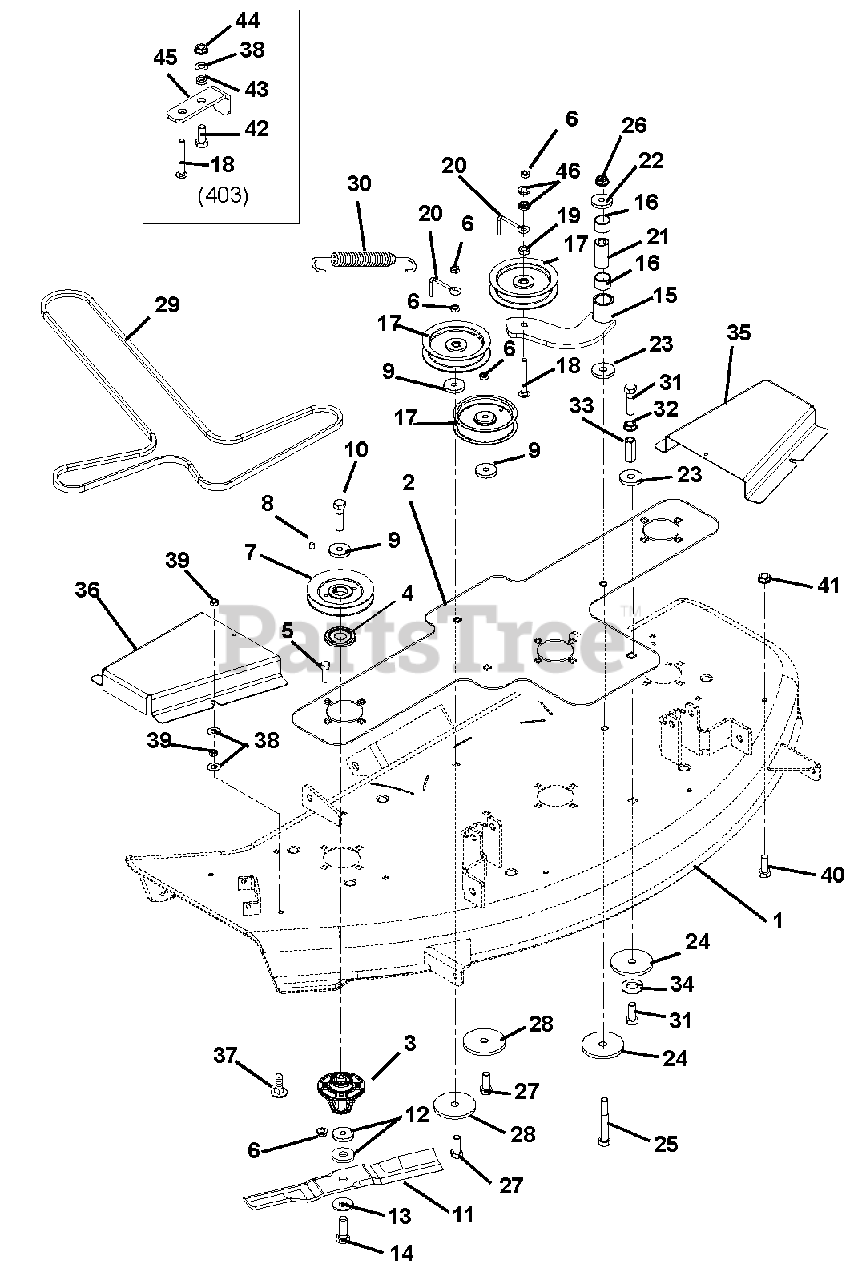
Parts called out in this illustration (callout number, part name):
1	Weldment 50" Deck (404)
2	Deck Doubler, (404)
3	Spindle Assembly
4	Dust Cap
5	Bolt, Round Head Square Neck .38-16 x 1.25
6	Nut .38-16 Flange Nyloc (404)
7	Sheave, Spindle 4.75 Dia. (404)
8	Key, Square .25 x .38 x .25
9	Washer, Flat Steel .406 x 1.50 x .245
10	Bolt, Hex .38-16 x 1.00 EP30 Grade 8
11	Blade, Mower (404)
12	Washer, Flat .640 x 1.81 x .250
13	Washer, Beveled .63 x 1.625 x .140
14	Bolt, Hex .62-18 x 1.75 Grade 8
15	Weldment, Idler Arm
16	Bearing, 1.00 x 1.12 x .75
17	Idler, Flat .38 x 4.00 x 1.06
18	Bolt, Round Head Square Neck .38-16 x 3.50 Grade 5 (404)
20	Finger, Belt (404)
21	Spacer, Powdered Metal
22	Washer, Flat Steel .511 x 1.44 x 125
23	Washer, Flat Steel .515 x 1.625 x .25
24	Washer, Flat Steel .531 x 3.00 x .25
25	Bolt, Hex .50-13 x 3.50 Grade 5
26	Nut, Locking-Top-Flange .50 - 13
27	Bolt, Hex .38-16 x 2.75 Grade 5
28	Washer, Flat Steel .469 x 2.00 x .25
29	V-Belt, HA x 140.2 EFF. (404)
31	Bolt, Hex .50-13 x 1.25 Grade 5
32	Nut, Spin Lock Flange .50-13
33	Nut, Coupling .50-13 x 1.75
34	Washer, Lock 1/2
35	Belt Cover, Left (404)
36	Belt Cover, Right (404)
37	Bolt, Round Head Square Neck .31-18 x 1.25 Grade 5
38	Washer, Flat Steel .38 x .875 x .083 (404)
39	Nut, .31-18 Nyloc Flange
40	Bolt, Hex .31-18 x .75 Grade 5 (404)
41	Nut, Spin Lock-Flange .312-18 (404)
42	Bolt, Hex .38-16 x 1.00 Grade 5 (403)
43	Bushing-Sleeve .377 x .624 x .235 (403)
44	Nut, Locking-Top-Flange .38-16 (403)
45	Belt Finger (403)
46	Bushing, Flange .406 x .88 x .270 x .140 (404)
